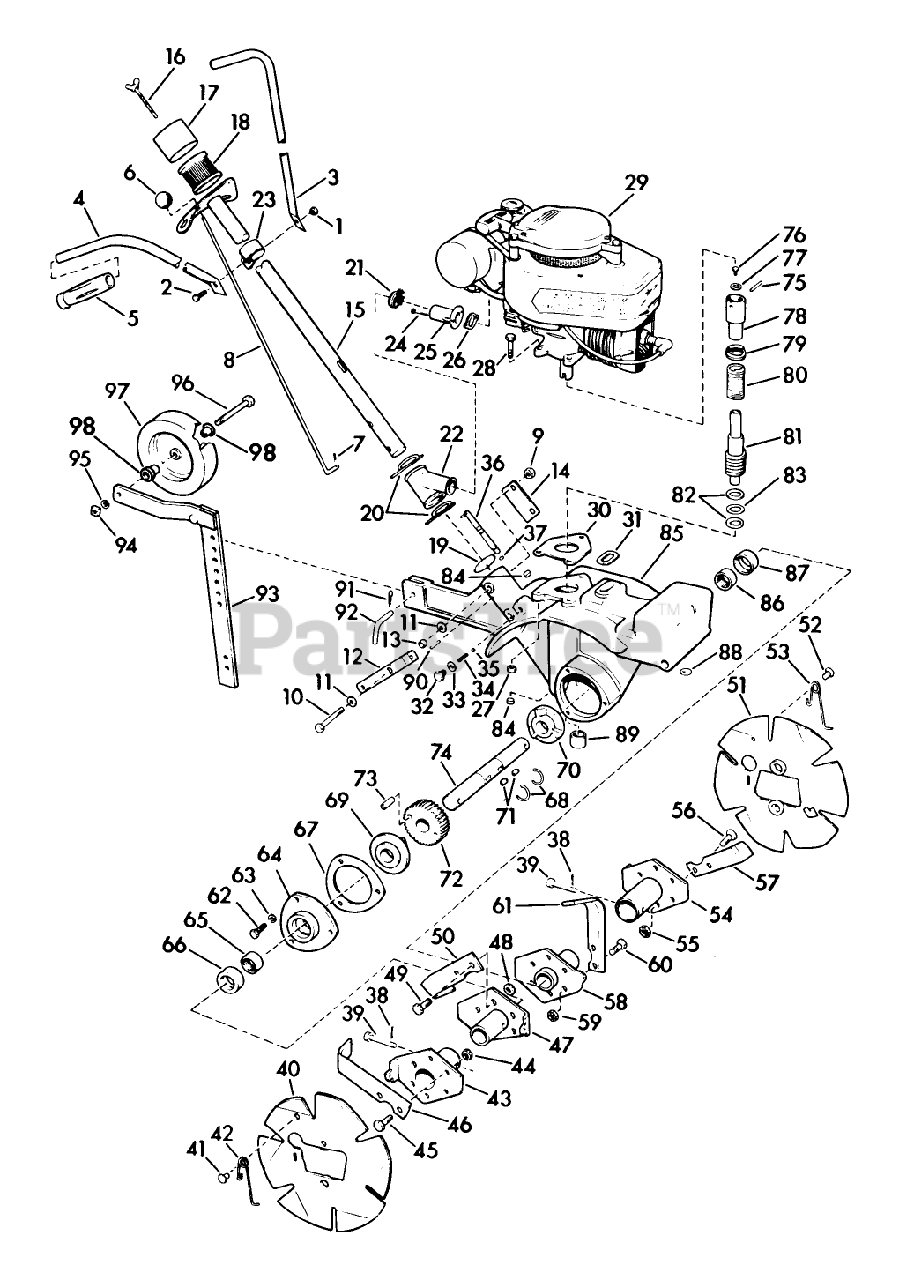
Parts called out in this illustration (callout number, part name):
3	Handlebar Section-Left
4	Handlebar Section-Right
6	Knob-Control Rod
7	Cotter Pin
8	Rod-Control
9	LOCKNUT
10	Screw-Hex Head Cap
12	Cotter Pin
13	Spacer-Control Rod Lever
14	Clamp-Handlebar Support Tube
19	Seal-Dust, Felt
20	Clamp-Hose
22	Tee-Carburetor, Rubber
23	Clamp-Handlebar
25	Tube-Carb. to Handle
32	Screw-Hex Head, Nylok
33	Washer-Plain, Aluminum
34	Spring-Detent
35	Ball-Detent
36	Clutch Pin Control Assy.
37	Ring-"O", Clutch Pin
39	Pin-Tine Assy. Attachment
41	Rivet-Shoulder
42	Spring-Trim Plate, Right
45	Screw-Hex Head Cap
46	Tine-Right Hand
49	Screw-Hex Head Cap
50	Tine-Right Hand
52	Rivet-Shoulder
53	Spring-Trim Plate, Left
56	Screw-Hex Head Cap
57	Tine-Left Hand
60	Screw-Hex Head Cap
61	Tine-Left Hand
65	Bearing
67	Gasket-Housing Cover
68	Ring-Retaining
70	Ratchet-Clutch, Left
72	Gear-Worm
73	Pin-Ratchet
74	Shaft-Worm Gear
75	Pin-Clutch
76	Screw-Hex Head, Nylok
77	Washer-Thrust
78	Coupling-Clutch Drum
79	Spring-Clutch Shock
82	Race-Thrust
83	Bearing-Needle Thrust
86	Bearing
89	Bearing-Closed End
92	Pin-Selector
95	WASHER, LOCK
